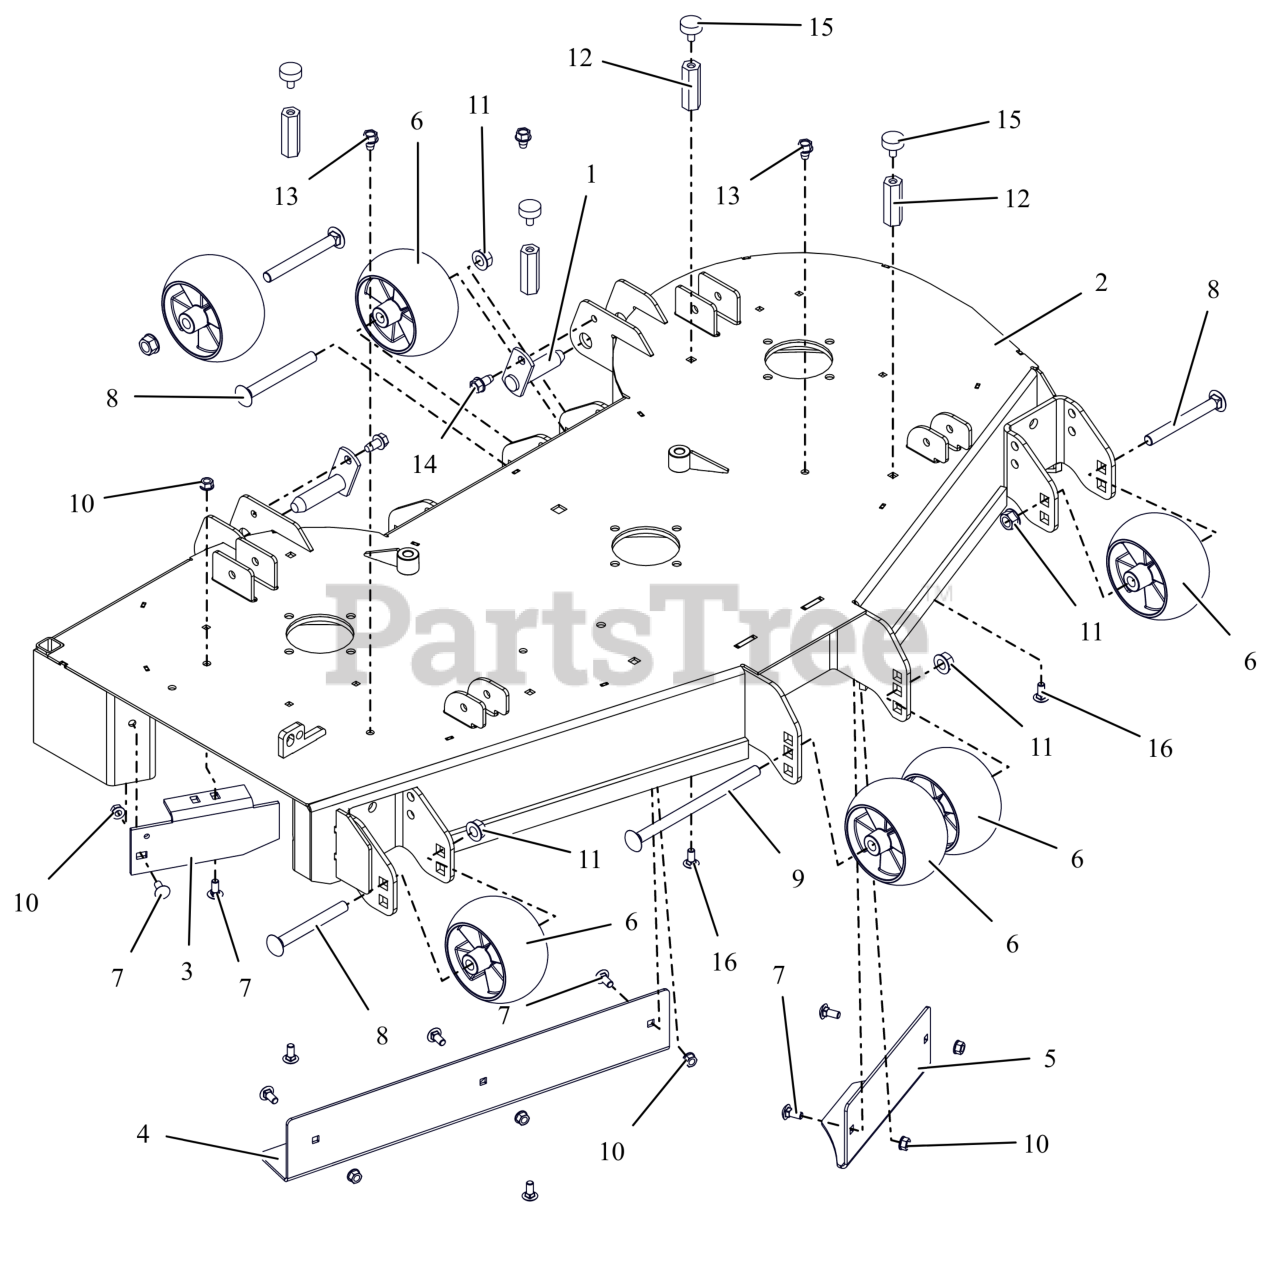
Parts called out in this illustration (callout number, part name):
1	WLDMT, MOWER MTG. PIN (BLACK)
2	KIT, 48" PRO-WALK DECK W/ DECALS (RED)
3	44"-48" SIDE DISCH BAFFLE -RED
4	BAFFLE, 48" RH VACUUM (RED)
5	BAFFLE, 44/48" LH VACUUM (RED)
6	WHEEL, ANTI SCALP - 5X3 CTR W/RIBS
7	BLT,RHSN .31-18X.75 G5 ZCC
8	BLT,RHNS .50-13X4.50 G5 ZCC NS
9	BLT,RHSN .50-13X8.00 G5 ZCC NS
10	NUT,LK-CTR-FLG .31-18 GF ZCC
11	NUT-LK-CTR-FLG .500-13 GG ZCC
12	NUT, .31-18X2.25 LG COUPLING
13	SCR,TAP .375-16X.50 HWH TR ZCC
14	SCR,TAP .375-16X.75 HWH TR ZCC
15	BUMPER, RUBBER
16	BTL,RHSN .313-18 X 0.75 G5 ZCC LT
